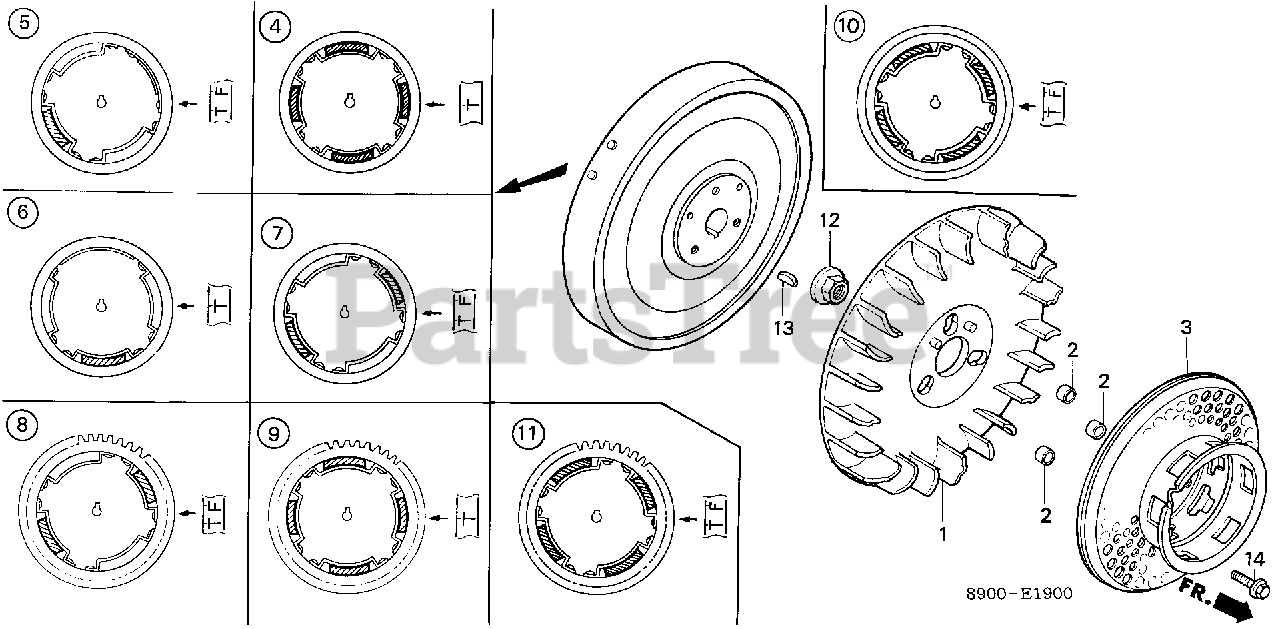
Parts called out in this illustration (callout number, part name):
1	FAN, COOLING
2	COLLAR, FAN
3	PULLEY, STARTER
6	FLYWHEEL (C.D.I.)
12	NUT, SPECIAL (16MM)
12	NUT, SPECIAL (16X1.5)
13	KEY, WOODRUFF (25X18)
14	BOLT, FLANGE (6X16)
